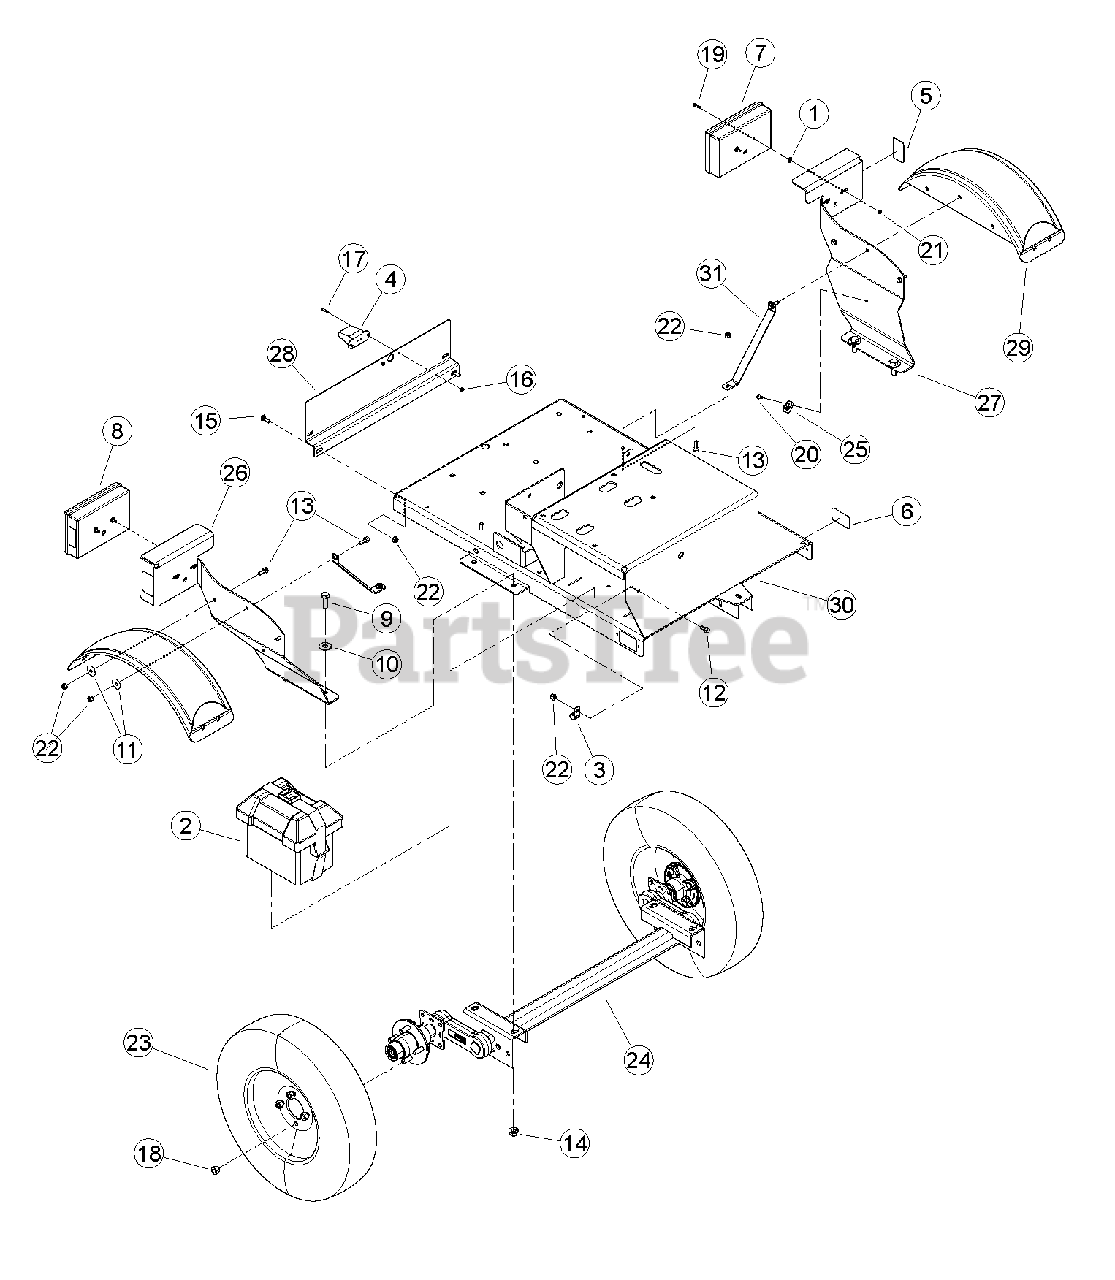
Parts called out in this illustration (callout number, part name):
1	GROMMET, 1/4 X 5/8 RUBBER
2	BOX, SMALL BATTERY
3	CLAMP, 9/16 COATED
4	LIGHT, LICENSE PLATE
5	REFLECTOR, WIDE ANGLE RED
6	REFLECTOR, WIDE ANGLE AMBER
7	LIGHT, TAIL RH
8	LIGHT, TAIL LH
9	BOLT, 1/2 X 1-1/2 HEX HD GR5 ZP
10	WASHER, 1/2" FLAT ZP
11	WASHER, 5/16" FENDER ZP
12	BOLT, 5/16 X 3/4 FLANGE NC
13	BOLT, 5/16 X 1 FLANGE NC
14	NUT, 1/2-13 NYLOCK FLANGE
15	BOLT, 5/16 X 1" GR5 CRG ZP
16	NUT, 10/24 NYLOCK TYPE NM, ZP
17	SCREW, MCH #10-24 X 3/4" PAN HD PH ZP
18	NUT, 1/2-20 WHEEL
19	BOLT, 10-24 X 3/4" HHCS GR8 PLAIN
20	RIVET, AL BLIND 1/4 X 3/4 DOME HEAD
21	NUT, #10-24 K-LOCK ZP
22	NUT, 5/16-18 NYLOCK-FLANGE
23	ASSEMBLY, 5.30-12 TIRE + SPOKE RIM
24	AXLE, 1000LB TORSION
25	CLAMP, CABLE MOUNT
26	BRACKET, RH FENDER "CE"
27	BRACKET, LH FENDER "CE"
28	PLATE, MOUNTING
29	FENDER, BLACK PLASTIC DRILLED
30	WELDMENT, C/S TRAILER
31	BRACE, FENDER
